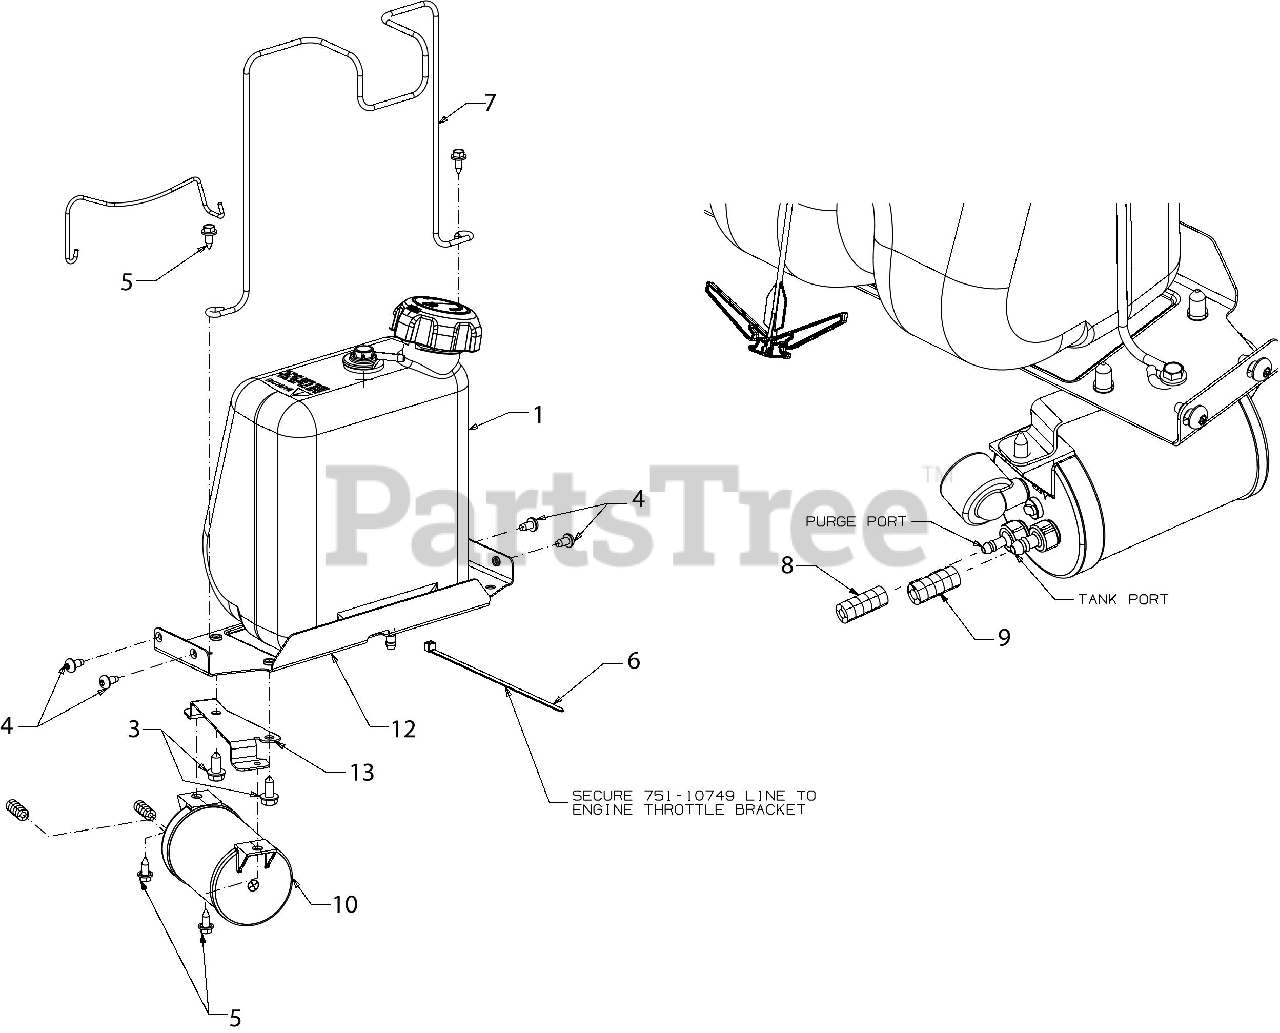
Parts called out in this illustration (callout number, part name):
1	FUEL TANK ASSEMBLY
2	BATTERY ROD ASSEMBLY
3	SCREW 5/16-18 x .750
4	SCREW 1/4-20 x .5
5	SCREW 1/4-20X.625
6	7" CABLE TIE
7	FUEL TANK SUPPORT ROD -
8	FUEL HOSE LOW PERMEATION
9	FUEL HOSE LOW PERMEATION
10	CARBON CANISTER
11	FUEL CAP W/TETHER
